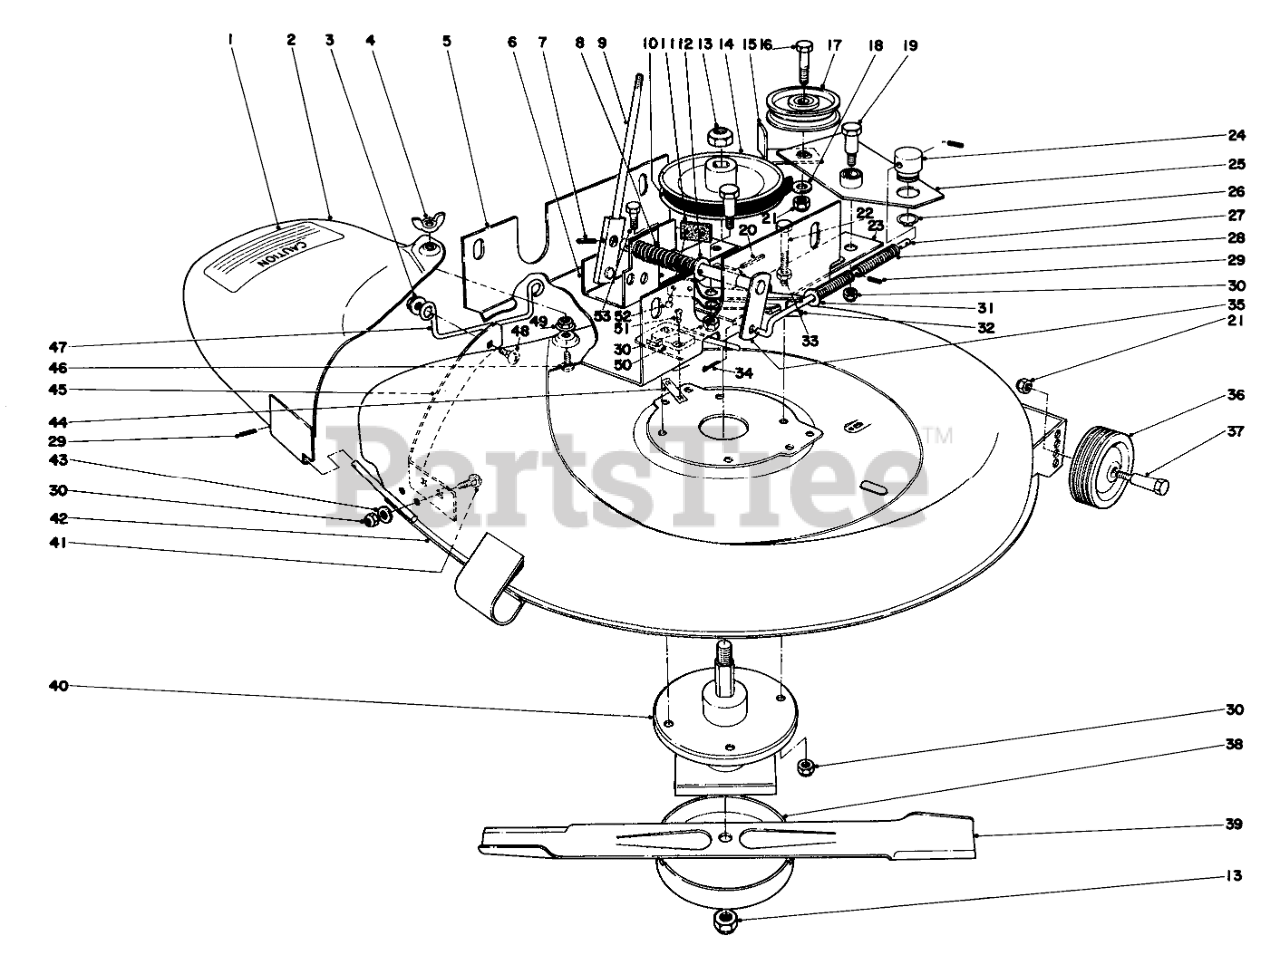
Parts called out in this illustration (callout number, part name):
1	Decal
2	Deflector
3	NUT-LOCK, HHF
4	Wing Nut
5	CHANNEL HT ADJ R
6	Mounting Bracket Blade
7	PIN-SPRING
8	COMP SPRING O
9	Deck Engagement Lever
10	V-Belt
11	BLADE BRAKE LINING
12	WASHER-FLAT
14	Pulley
15	Belt Retainer
16	SCREW-HH
17	Flat Idler
18	WASHER-FLAT
19	CLUTCH PIVOT BOLT
20	PIN-SPRING
21	Nut
22	SCREW-HH
23	Bracket Idler Mounting
24	Pivot Pin
25	Idler Arm
26	RING-RETAINING
27	Blade Engage Rod
28	DECK IDLER SPRING
29	PIN-SPRING
30	NUT-LOCK, CONE
31	WASHER
32	Blade Brake
33	NUT-JAM
34	PIN-COTTER
35	Linkage
36	Wheel
38	Cup
39	Blade
40	Mower Spindle
41	BOLT-CARR
42	Housing
43	WASHER-FLAT
44	NUT-SPEED
45	Bar-Deflector
46	BOLT-CARR
47	Bracket Foot Guard
48	SCREW-CARRIAGE
49	PAL NUT
50	MICRO SWITCH
51	SCREW-SPH
52	Rivet
53	SCREW-HH
